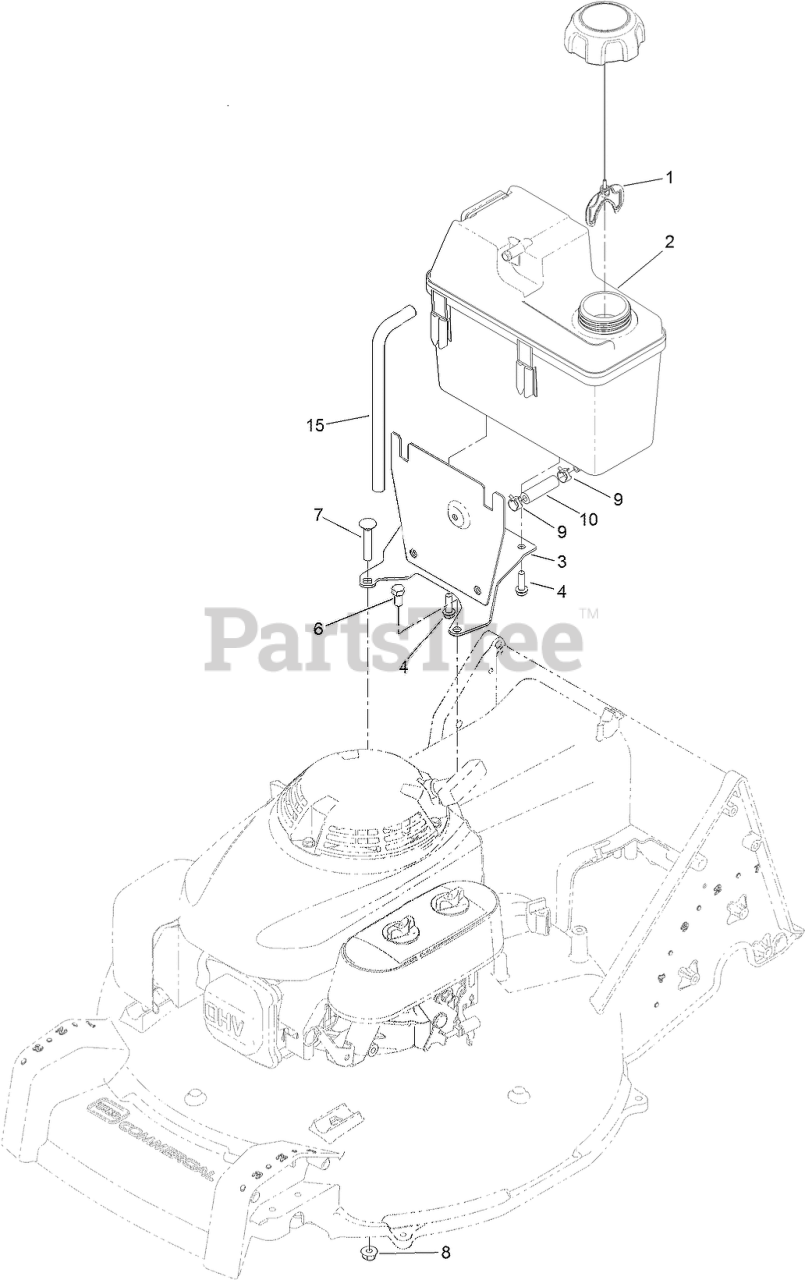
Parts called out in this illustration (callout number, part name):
1	CAP-RATCHET, TETHERED
2	TANK-FUEL
3	MOUNT-TANK
4	SCREW-HWH
6	SCREW-HH
7	SCREW-CARR
8	NUT-HF, NI
9	CLAMP-HOSE
10	HOSE-FUEL
15	HOSE-VENT, CANISTER
